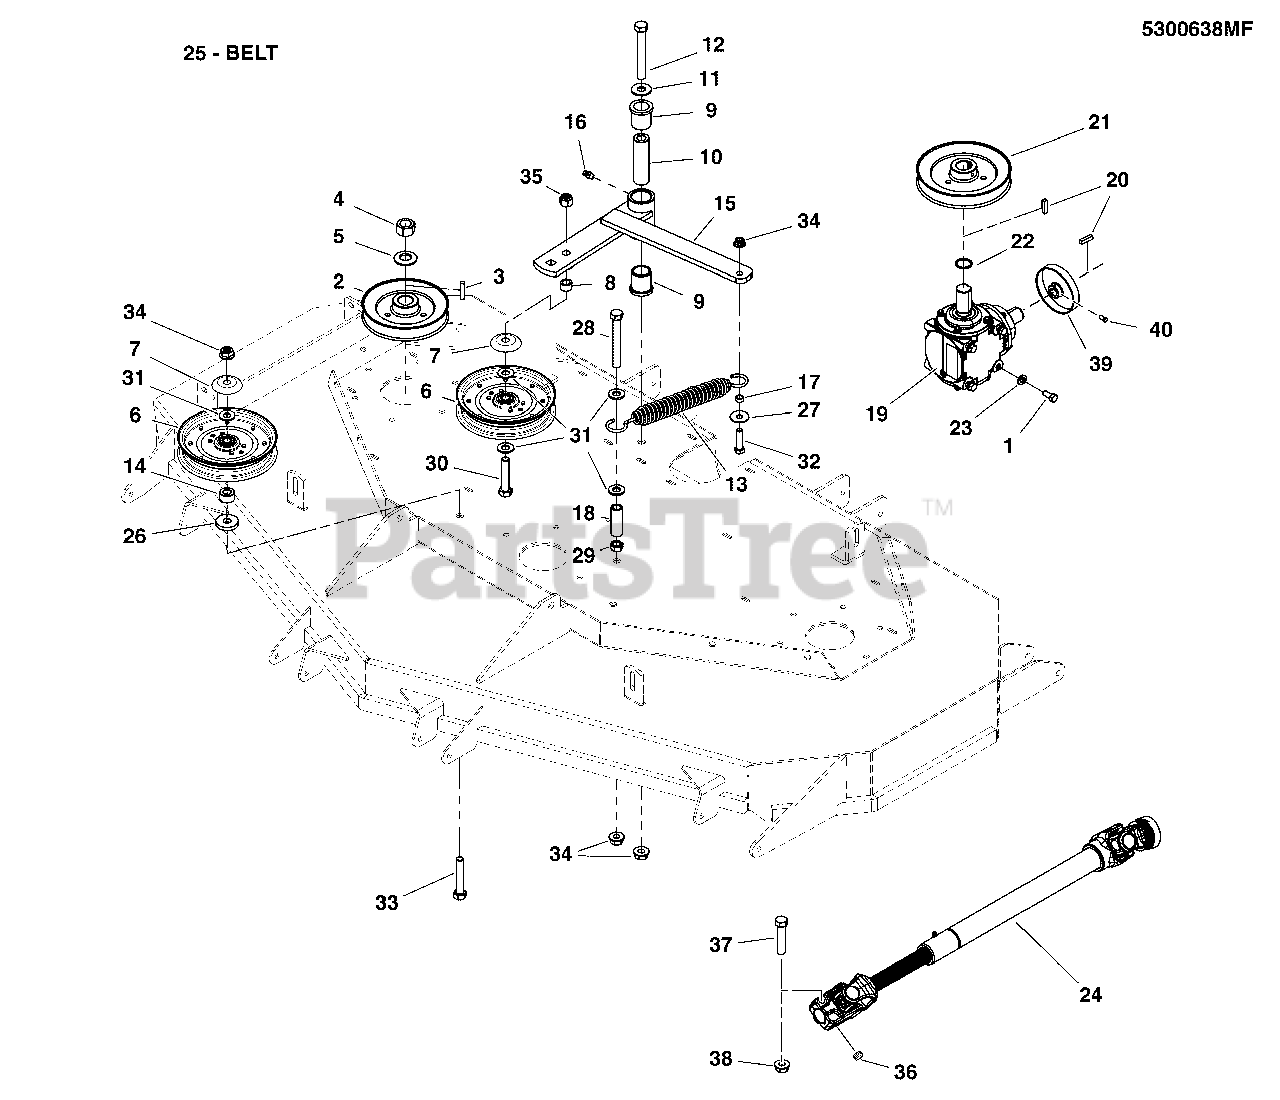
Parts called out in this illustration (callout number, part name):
1	BOLT, 5/16-18 X 3/4 GD5
2	PULLEY, 5.540OB X 3985ID, SINGLE B-SEC
3	KEY, 1/4 SQ. X 1-1/4
4	WASHER, 3/4 BELLEVILLE
5	NUT, 3/4-16 HEX
6	*PULLEY, FLAT IDLER, 6-3/4"
7	SHIELD, PULLEY BEARING
8	SPACER, .52 X 1.00 X .63, YZ
9	BUSHING, FLANGE
10	SPACER, .52 X 1.00 X 3.50
11	WASHER, 1/2 USS
12	BOLT-1/2-13 X 5 GD5 YZ
13	SPRING, EXTENSION, SWIVEL, SHORT HOOK
14	SPACER, .52 X 1.00 X .56, YZ
15	WELD, IDLER ARM - OUTFRONT - RED
16	GREASE FITTING, 1/4-28 STRAIGHT
17	SPACER, .38 X .50 X .27
18	HOSE, 1/2" PUSH-ON 2.125"
19	GEAR BOX, RIGHT ANGLE
20	KEY, 1/4 SQ. X 1.00
21	PULLEY, 6.25" SPLIT STEEL W/ 1" ID
22	SNAP RING, EXTERNAL, 1 SHAFT
23	WASHER, 5/16 LOCK YZ
24	SHAFT, TELESCOPING DRIVE, OUT-FRONT
25	BELT, #7-3556
26	WASHER, .53 X 1.50 X .25
27	WASHER-3/8 FENDER
28	BOLT, 1/2-13 X 4 GD5 YZ
29	NUT, 1/2-13 HEX JAM
30	BOLT, 1/2-20 X 2-1/2 GD5 YZ
31	WASHER, 1/2 SAE
32	BOLT, 3/8-16 X 1-1/4 GD5
33	BOLT, 1/2-13 X 2-3/4 GD5
34	NUT, 1/2-13 HEX NYLOCK FLANGE
35	NUT, 1/2-20 HEX NYLON LOCK
36	SET SCREW, 3/8-16 X 3/8
37	BOLT, 3/8-16 X 1-3/4 GD5
38	NUT, 3/8-16 HEX NYLON LOCK
39	GUARD, TRASH, S800X
40	SOC SET SCREW, 1/4-20X3/8, DRI-LOC PATCH
